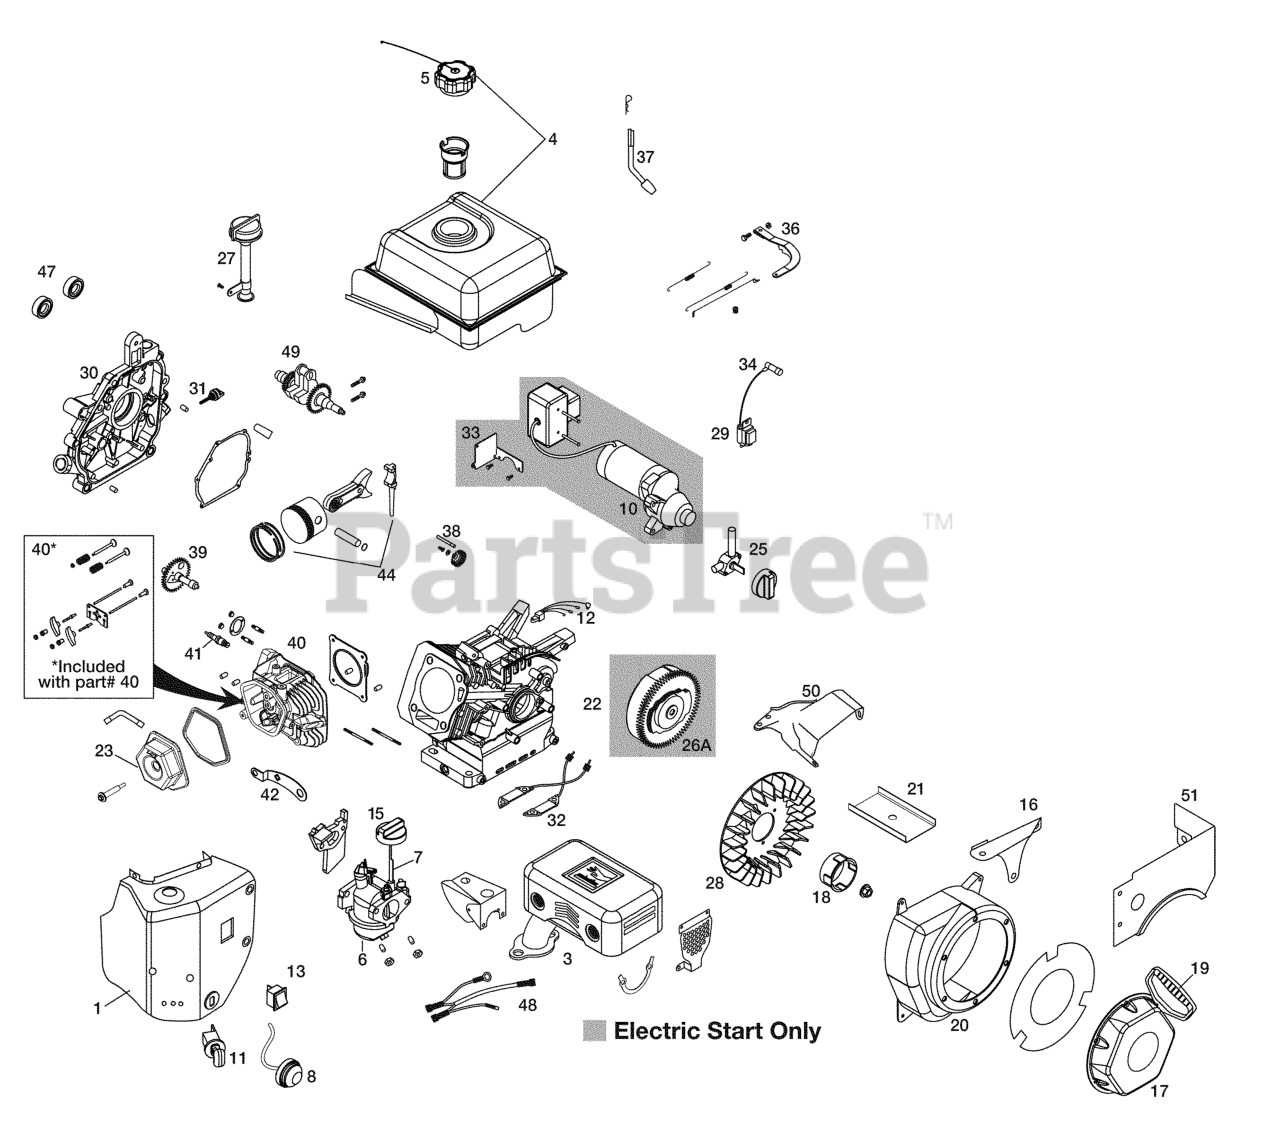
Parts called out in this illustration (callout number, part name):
1	HEATER.BOX.ASSY-SNW(SKSN4100)
3	MUFFLER.ASSY.SNOW(SKSN4200)
4	FUEL.TANK.ASSY.SNOW(SKSN4300)
5	FUEL.TANK.CAP.SNOW(SKSN4301)
6	CARBURETOR.ASSY.SNOW(SKSN4302)
7	CHOKE.LVR.CARB.SNOW(SKSN4303)
8	PRIMER.BULB.ASSY(SKSN4304)
10	ELEC.START.ASSY.SNOW(SKSN4400)
11	KEY.SWITCH.ASSY.SNOW(SKSN4401)
12	CDI.BOX.ASSY.SNOW(SKSN4404)
13	ON/OFF.SWITCH.SNOW(SKSN4403)
15	CHOKE.KNOW.SNOW(SKSN4500)
16	CHUTE.LOWER.BAGGER.30"(2 2 BR)
17	RECOIL.START.ASSY.SNW(SKSN4600
18	STARTER.CUP.SML.SNOW(SKSN4601)
19	STARTER.GRIP.SNOW(SKSN4603.1)
20	BLOWER.HSG.ASSY.ELEC(SKSN4602
21	SHIELD.CYLINDER.SNOW(SK4141010
22	SHIELD.U/FYWHL.CHARG(SKSN4604)
23	VALVE.COVER.LCT.414CC.
25	FUEL.PETCOCK.SNOW(SKSN4900)
26	FLYWHEEL.ASSY.ELEC.START
26A	FLYWHEEL.ASSY.MAN.START
27	HIGHOIL.FILL.ASSY.KIT(SKSN4911
28	FLYWHEEL.FAN(SK4144000)
29	IGNITION.COIL.ASSY
30	CRANKCASE.CVR.ASSY(SK4143600)
31	NONREMVABLE.OIL.PLUG(SK4143715
32	CHARGING.COIL.AC/DC(SK4141710)
33	ELECTRIC.START.BRKT(SKSN4405)
34	SPARK.PLUG.BOOT
36	GOVERNOR.ARM.ASSY(SKSN4502)
37	GOVERNOR.SHAFT(SK4143100)
38	GOVERNOR.GEAR.ASSY(SK4142900)
39	CAMSHAFT(SK4141600)
40	CYLINDER HEAD ASSY
41	SPARK.PLUG(SK2911550)
42	CDI.BOX.BRKT.SNOW(SKSN4402)
44	PISTON.AND.ROD.ASSY(SK4141400)
46	SHIELD.VAPOR(SKSN4606)
47	OIL SEAL KIT NON-GENERATOR
48	WIRE.HARNESS(SKSN4406)
49	CRANKSHAFT.KEYED
50	RP TOP SHIELD
51	SKIRT FUEL TANK
